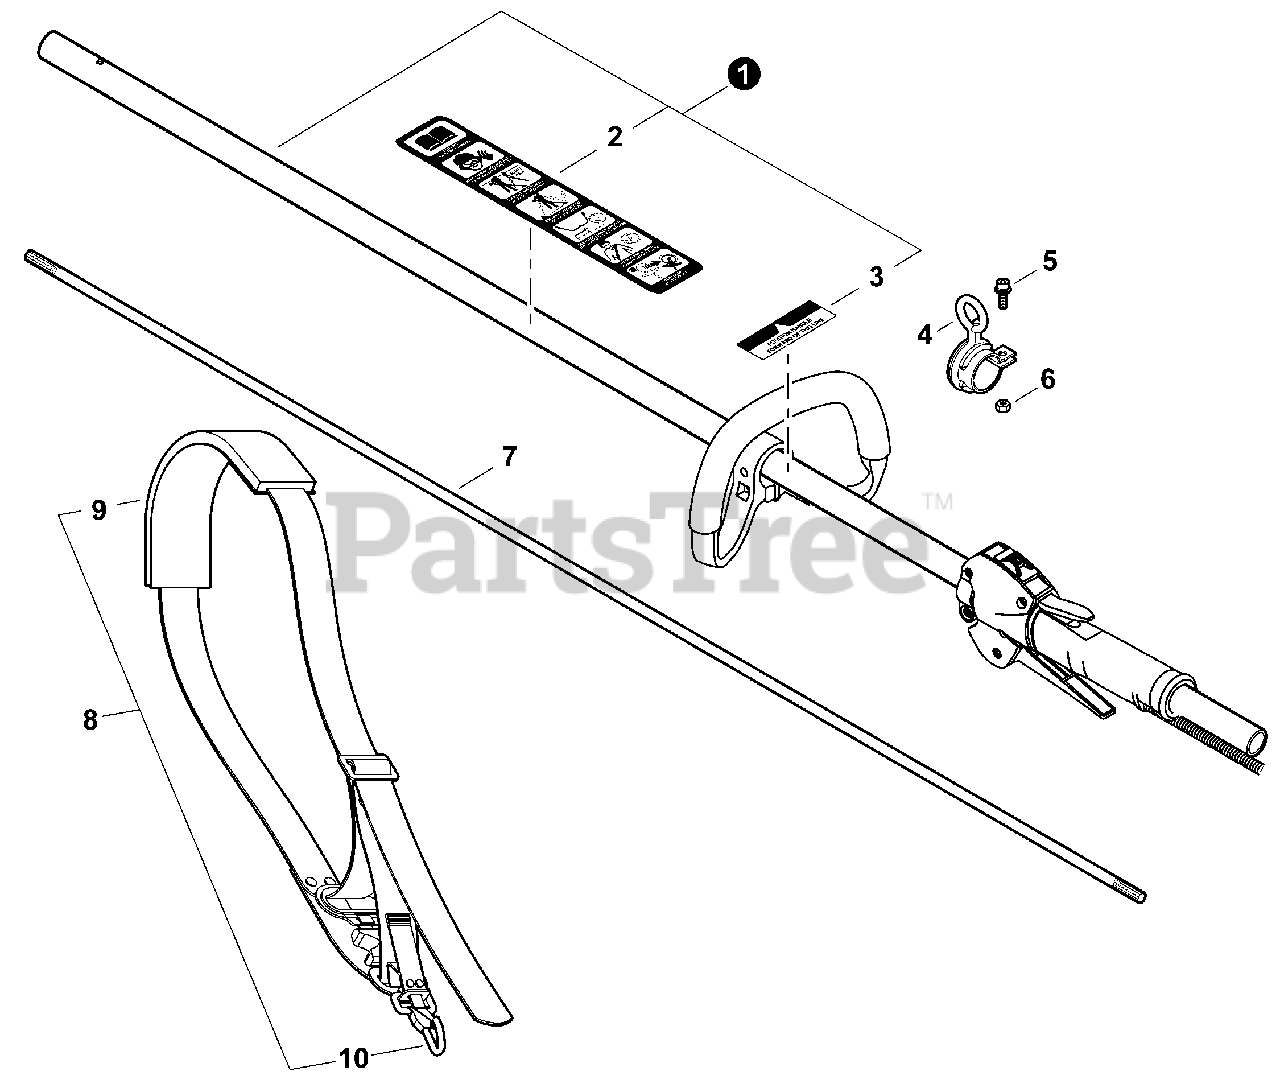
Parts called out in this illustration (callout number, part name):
1	MAIN PIPE ASSY
2	LABEL, CAUTION (BLADE CAPABLE)
3	LABEL, HANDLE
4	HANGER, SWIVEL
5	BOLT 5
7	MAINSHAFT
8	HARNESS ASSY, SHOULDER
9	PAD, SHOULDER
10	HOOK, SNAP
